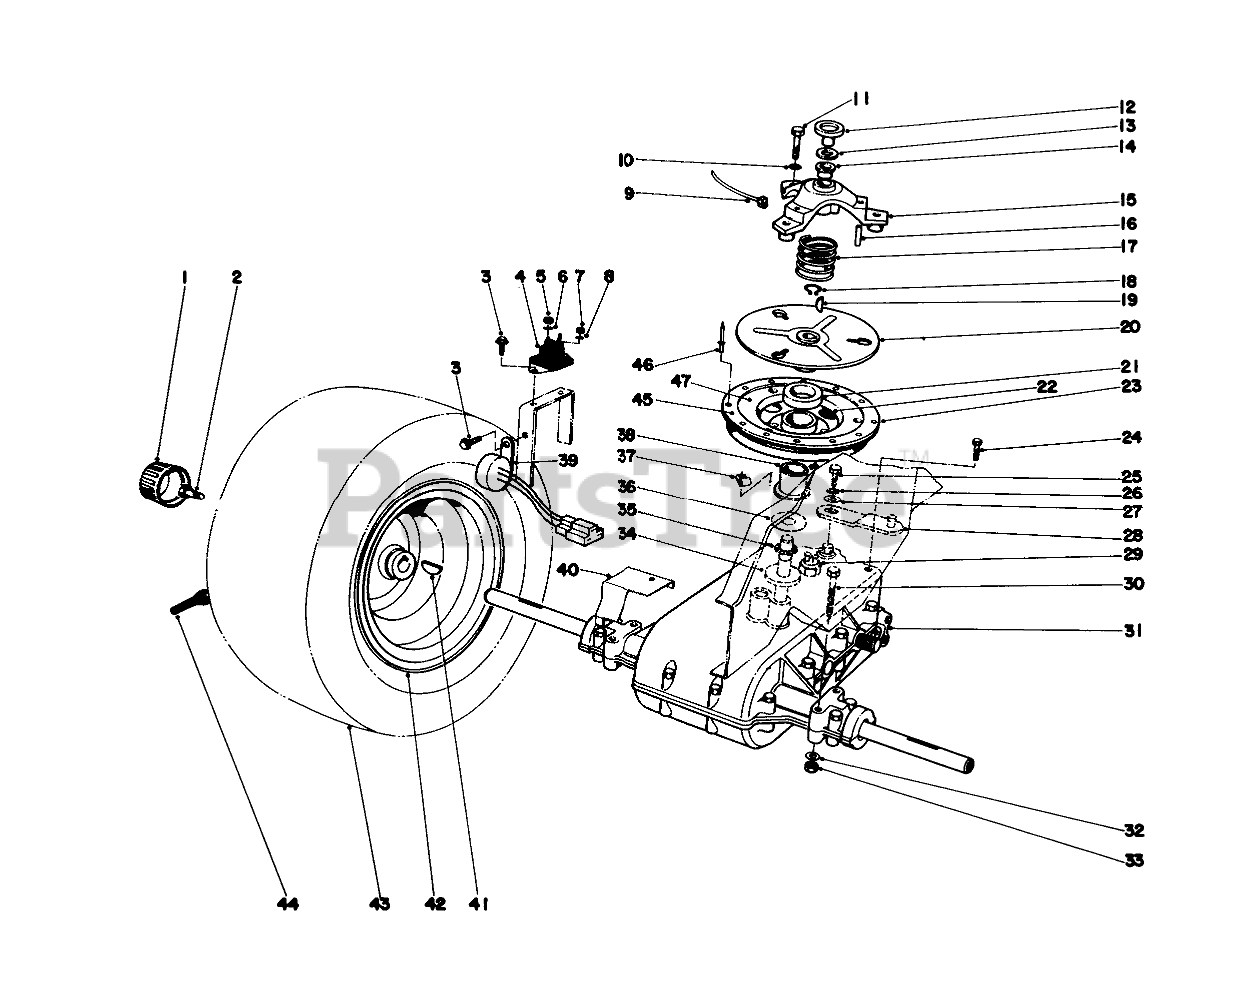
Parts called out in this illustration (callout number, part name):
1	Cap-Hub
2	CAPSCREW 3/8 16 3/4
3	Screw
4	SOLENOID
5	NUT-JAM, BRASS
6	WASHER-LOCK
7	NUT-HEX
8	WASHER-LOCK
9	TIE-MOUNT, PUSH
10	WASHER-LOCK
11	SCREW-HH
12	CLUTCH CAP
13	THRUST RACE
14	BUSHING-FLANGE
15	Cover Assembly (Incl. Ref. #14 & 16)
16	NEEDLE BRG
17	COMPRESSION SPRING
18	RING-SNAP, EXTERNAL
19	KEY-WOODRUFF
20	Clutch Plate
21	WASHER FELT
23	Sheave Assembly (Incl. Ref. #38 & 45-47)
24	SCREW-HWHTF
25	SCREW-HH
26	WASHER-LOCK
27	WASHER-FLAT
28	SHIFT LEVER WA B
29	NEUTRAL SWITCH
30	SCREW-HH
31	Transaxle
32	WASHER-PLAIN
33	NUT-LOCK, CONE
34	THRUST WASHER
35	NEEDLE BRG
36	THRUST WASHER
37	CLIP-FUEL LINE
38	Bushing
39	Module Interlock
40	GRASS SHIELD B
41	WOODRUFF KEY
42	Rim
43	16 X 7.5-8 REAR TIRE
44	STEM-VALVE
45	CLUTCH PAD
46	RIVET-POP
47	Retainer Ring
